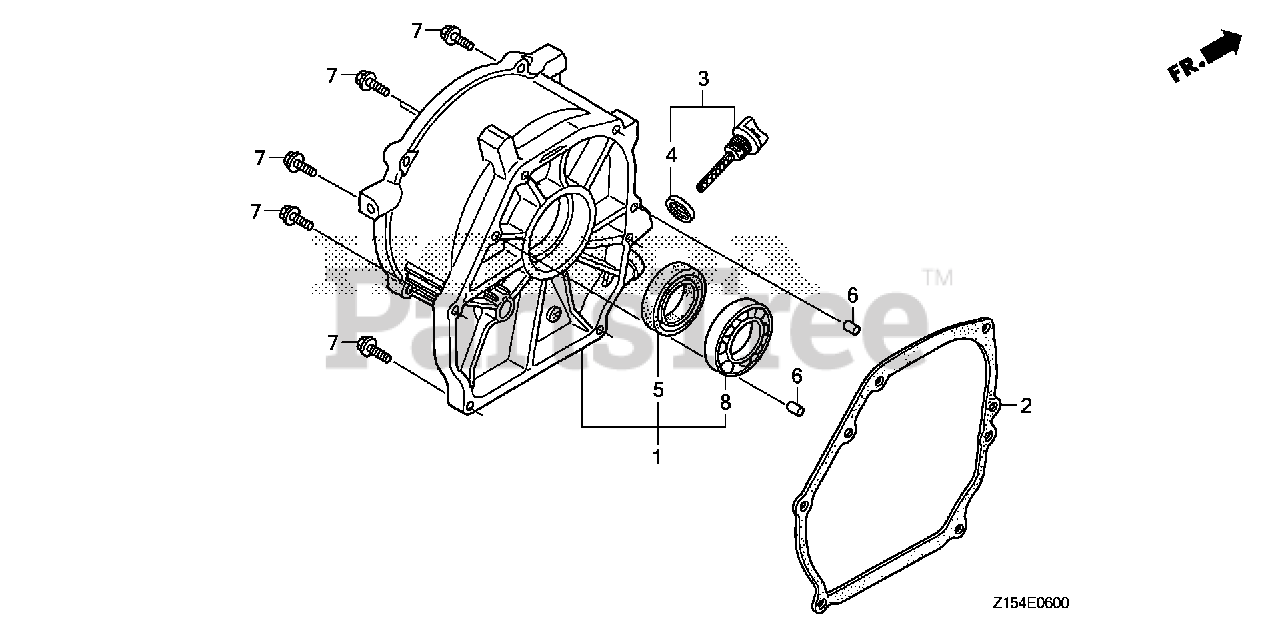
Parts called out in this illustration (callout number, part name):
1	COVER ASSY., CRANKCASE
2	GASKET, CASE COVER (NON-ASBESTOS)
2	GASKET, CASE COVER (NINGBO SIL GASKET)
3	CAP ASSY., OIL FILLER (GRAY)
4	GASKET, OIL FILLER CAP
5	OIL SEAL (25X41X6)
6	PIN, DOWEL (8X14)
7	BOLT, FLANGE (8X32)
8	BEARING, RADIAL BALL (6205)
